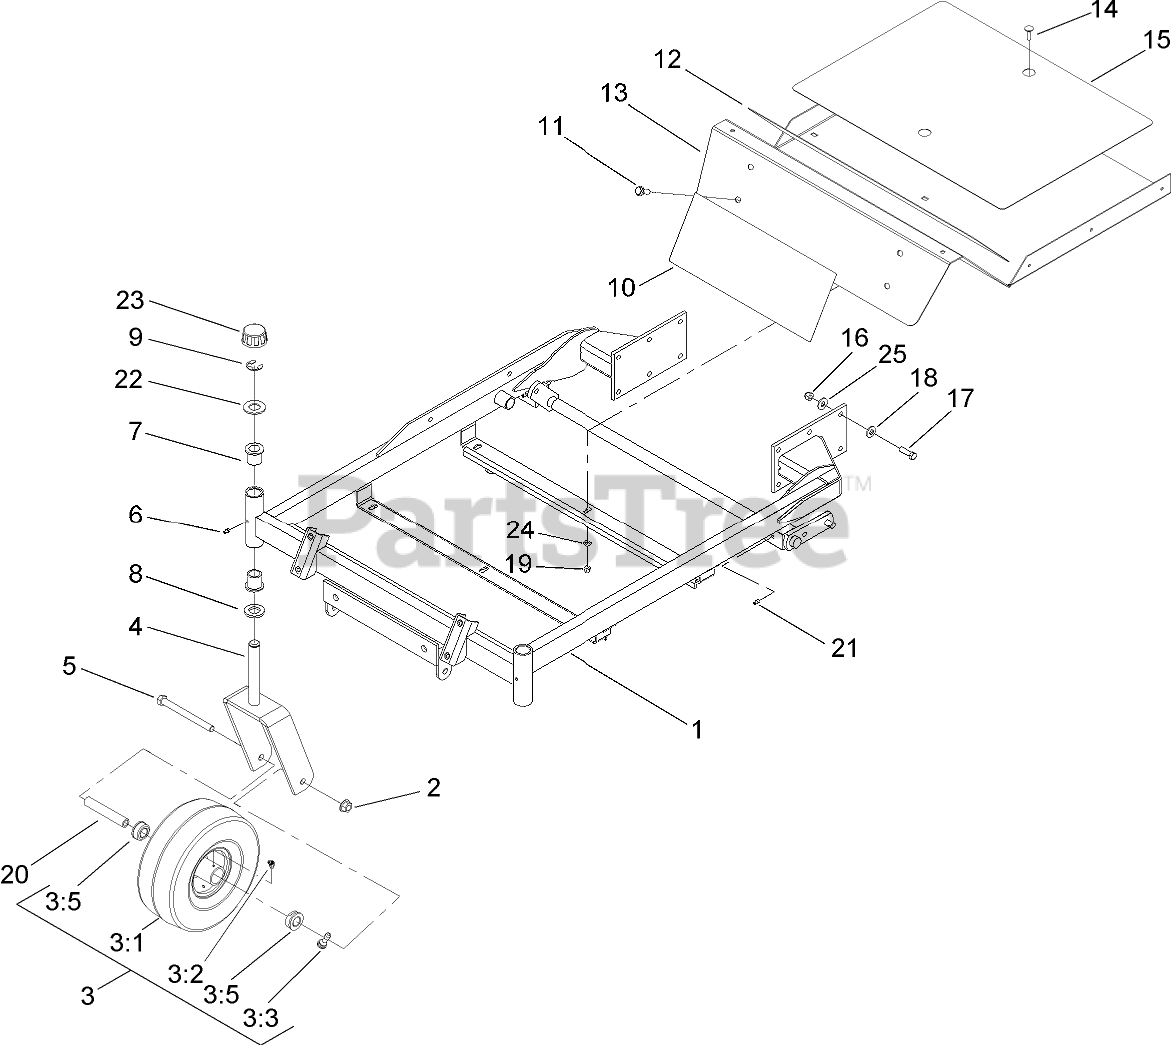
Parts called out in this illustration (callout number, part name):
1	CARRIER FRAME ASM
2	NUT-HF
3	FRONT WHEEL AND TIRE ASM
3:2	FITTING-GREASE
3:3	STEM-VALVE
3:5	BUSHING-FLANGE
4	CASTER FORK ASM
5	SCREW-HH
6	FITTING-GREASE
7	BEARING-FLANGED
8	WASHER-FLAT
9	RING-RETAINING, EXT
10	DECAL
11	SCREW-HHF
12	PAD-SKID, ANTI
13	FLOORPAN
14	SCREW-CARR
15	PAD-SKID, ANTI
16	NUT-LOCK, NI
17	SCREW-HH
18	WASHER-BELLEVILLE
19	NUT-LOCK, NI
20	BUSHING-SPANNER
21	FITTING-GREASE
22	WASHER
23	CAP-HUB
24	WASHER-PLAIN
25	WASHER-HARDENED
